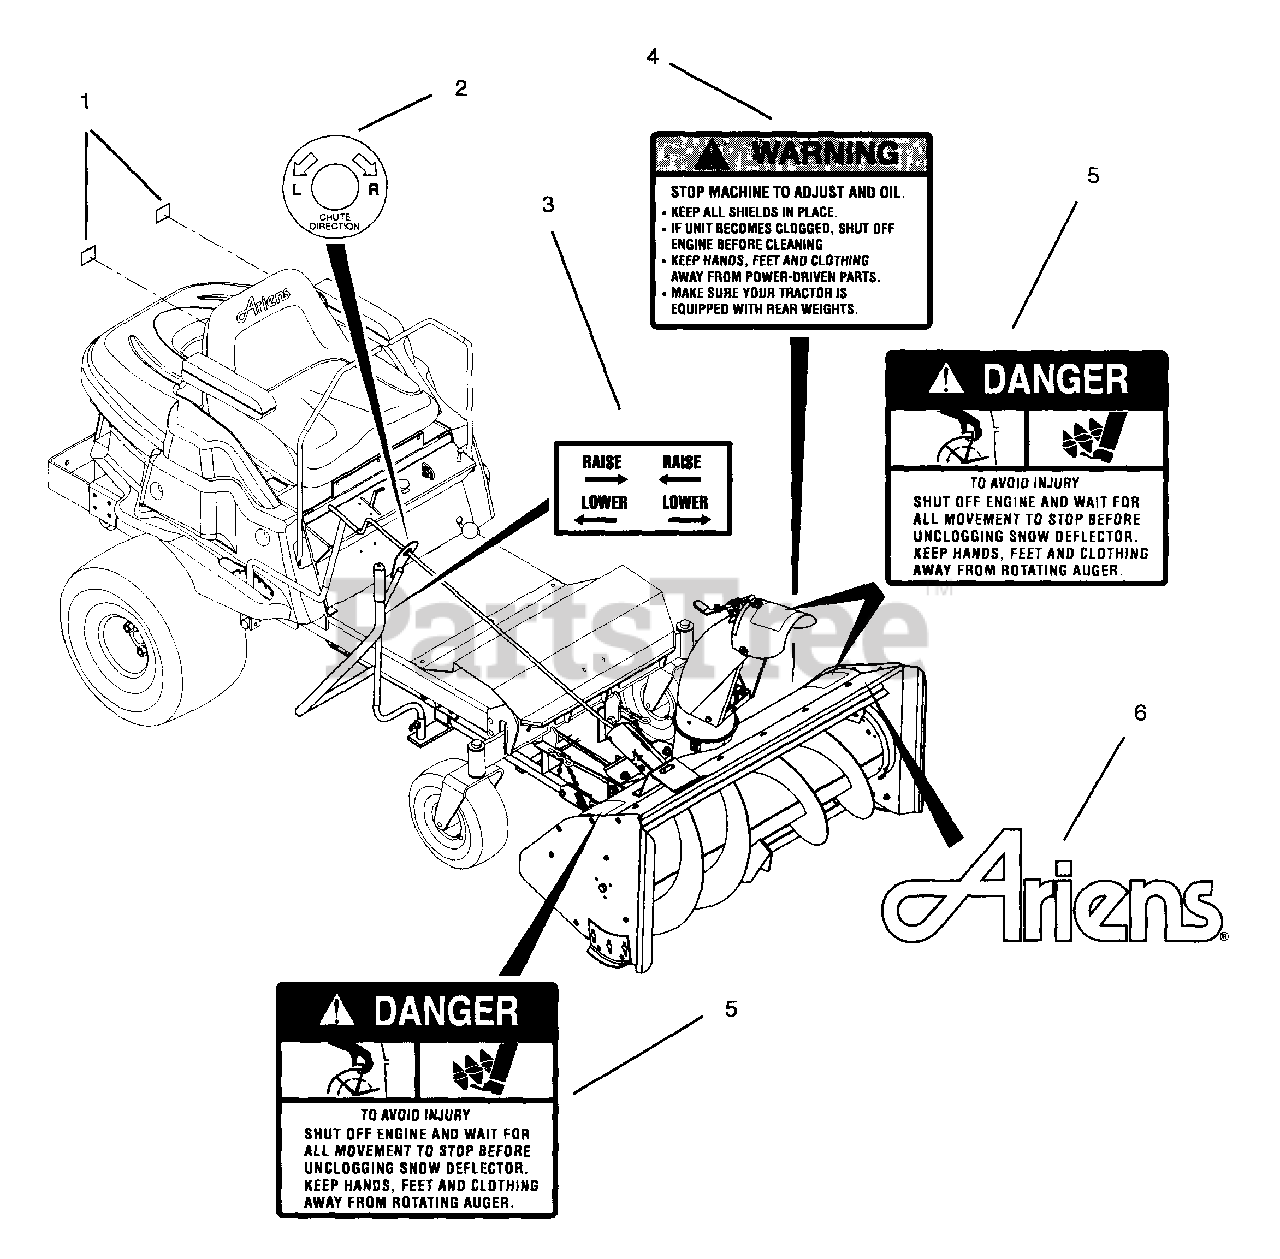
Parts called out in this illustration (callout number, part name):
1	REFLEX REFLECTOR
2	RIGHT & LEFT DECAL
3	RAISE & LOWER DECAL
4	DECAL, WARNING
5	DECAL, DANGER
6	DECAL-ARIENS
